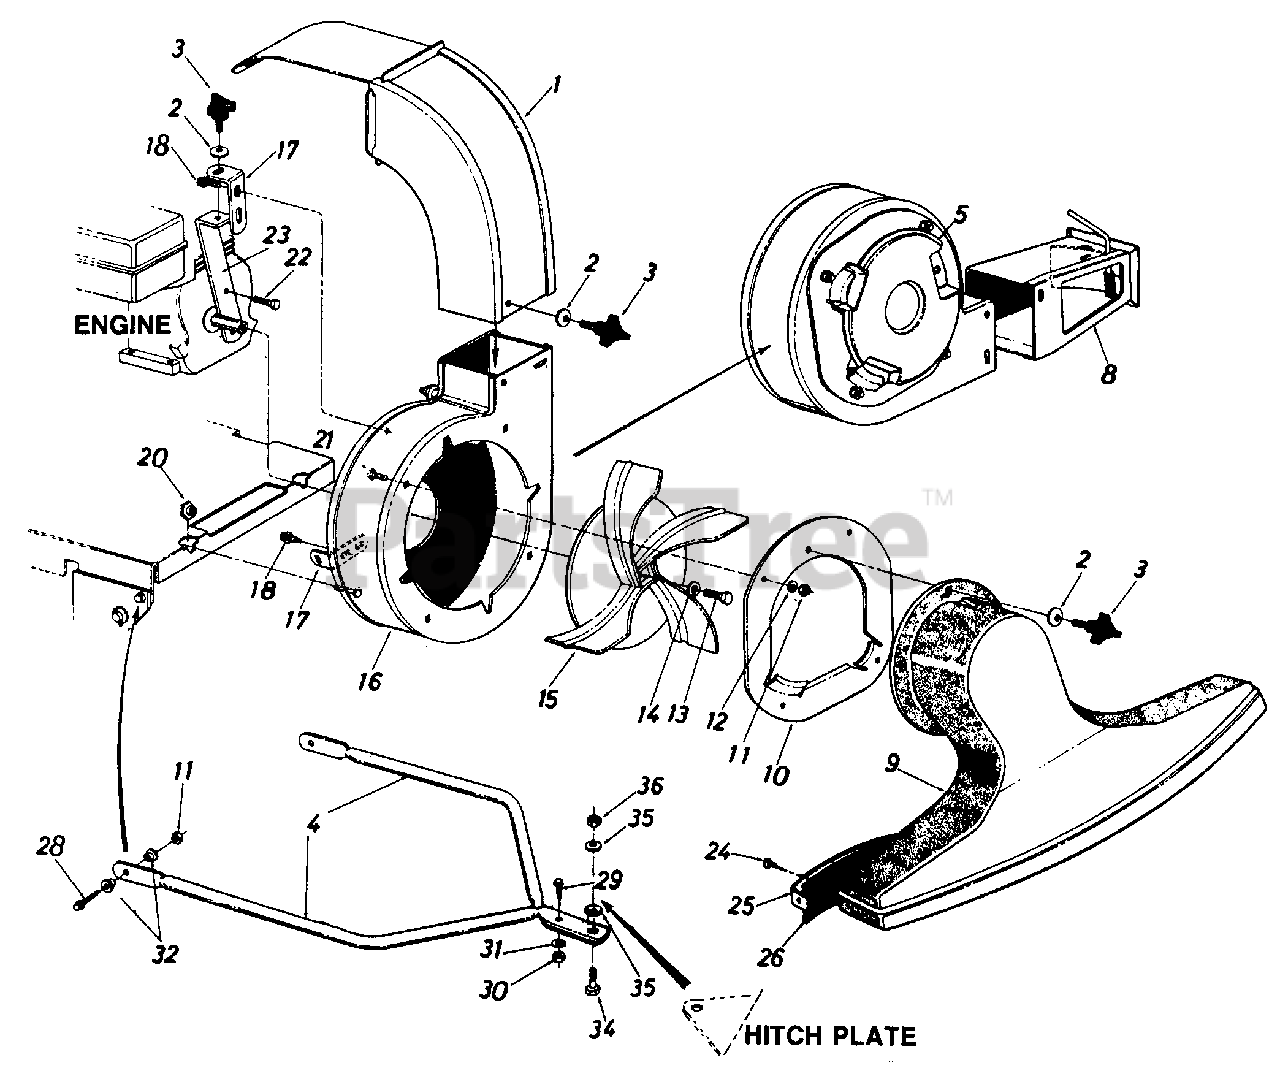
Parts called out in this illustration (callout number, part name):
3	KNOB-THREE ARM
10	PLATE ASSY-NOZZLE
11	NUT-HEX 5/16-18
12	WASHER-LOCK-5/16
13	SCREW 3/8-24 X 1.25 GR5
14	WASHER-HDL 3/8
15	PLATE ASSY-VANE
20	NUT-HEX SHLD
21	BOLT-CARRIAGE 5/16-18 X .62
22	SCREW-CAP LOCK 5/16-24 X .75
28	SCREW-HEX WASH TAPP 5/16-18X1.0
29	SCREW-TRUSS MACH
30	NUT-HEX 1/4-20
31	LOCK WASHER 1/4 DIA
32	SPACER-SHLD
34	SCREW-SHLD .498 DIA X .340
35	WASHER-BELL .3/8ID X 1.12OD X .030
36	NUT-HEX TOP LOCK-3/8-16
